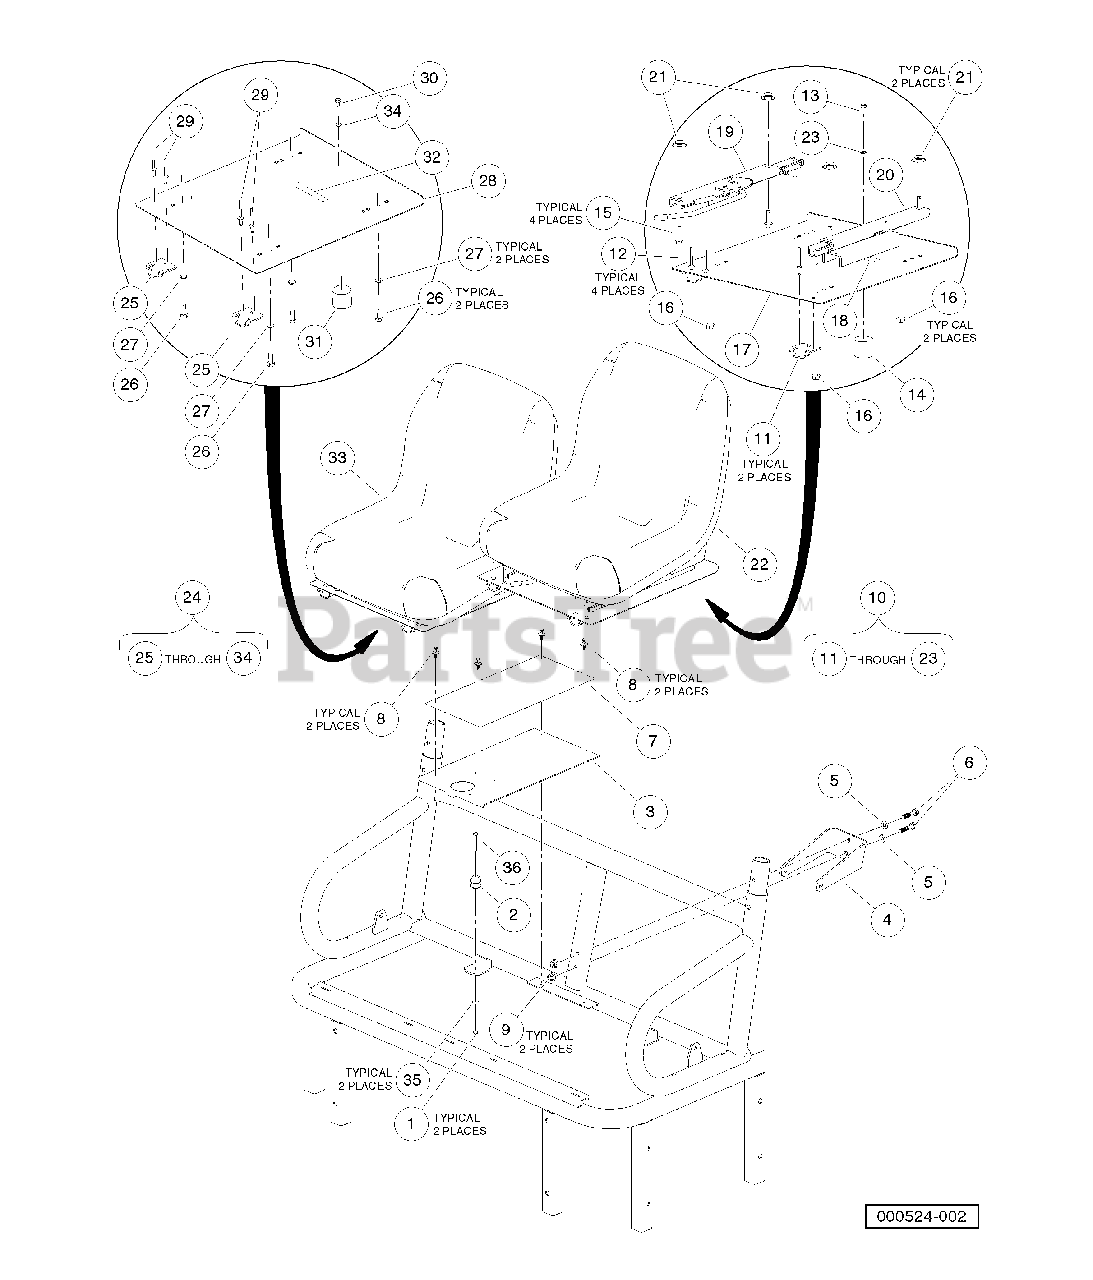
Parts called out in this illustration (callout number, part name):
1	Locknut, 25 M6-1.00 Nylon Insert
2	Seat Holder Base
3	Pan, Center, Closeout
4	Bracket, Seatbelt, Bolt-On
5	Washer, Hard, M10, Zn-Ni/Blk
6	Bolt, M10 X 45, Zn-Ni
7	Cover, Center Console
8	Rivet, Removable, Tuflok 1/4"
9	Nut, Flanged, M10 x 15, Black
10	Asm, Bracket Seat, Adj, Blk
11	Hinge Plate
12	Rivet, 1/4 X .438 Blind
13	Screw, 6m-100 X 10mm Hex Head
14	Seat Holder Cup
15	Bolt, Flange Head, M8 X 30.0
16	Nut,m8,all Metal Lock
17	Pan, Seat, Driver Asm
18	Decal, Hot Surface Warning
19	Adjuster, Forward/Aft
20	Adjuster, Slider
21	Washer, Bell
22	Seat, Bucket, Black
23	Lockwasher, 1/4 Helical Split
24	Asm, Bracket Seat, Passenger, Blk
25	Hinge Plate
26	Screw, M8-125 X 22 Hex-Head
27	Lockwasher, 8mm Split
28	Pan, Seat, Passenger
29	Rivet, 1/4 X .438 Blind
30	Screw, 6m-1.00 X 10mm Hex Head
31	Seat Holder Cup
32	Decal, Hot Surface Warning
33	Seat, Bucket, Black
34	Lockwasher, 1/4 Helical Split
35	Washer, 1/4 Type A Narrow Flat
36	Bolt, M6 X 1 X 45
